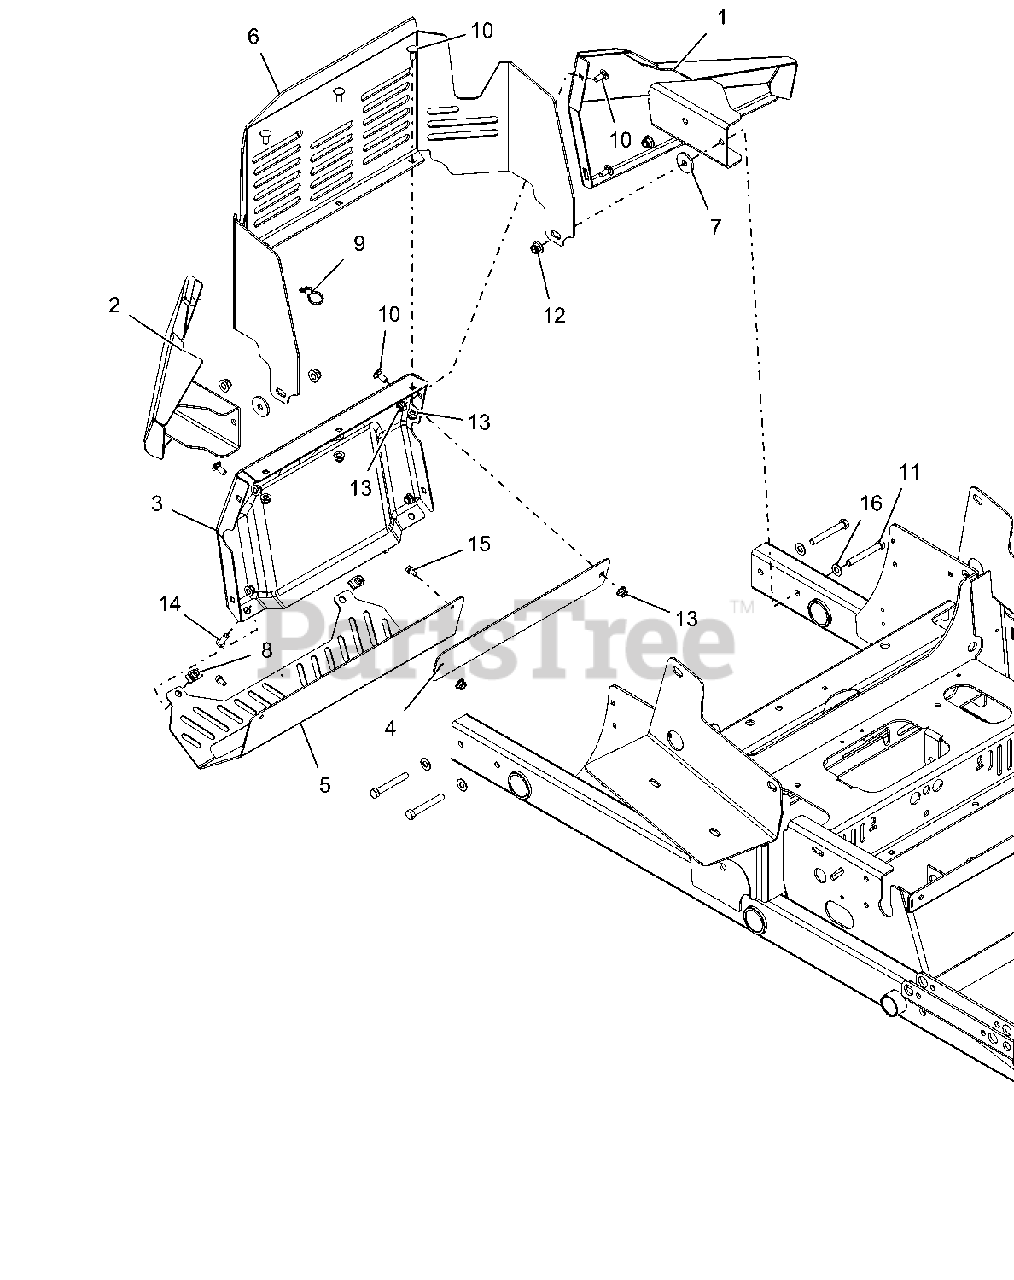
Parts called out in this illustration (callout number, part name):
1	WLDMT, LEFT REAR BUMPER WING (BLACK)
2	WLDMT, RIGHT REAR BUMPER WING (BLACK)
3	BUMPER, PT200/400 REAR (BLACK)
4	PLATE, BACKER (RED)
5	GUARD, PT200/400 MUFFLER (BLACK)
6	GUARD, PT200 ENGINE (RED)
7	WSHR-FL-STL .406X1.375X.135 YZ
8	NUT-CLIP RETAINER 5/16-18X.56
9	CABLE TIE W/ TREE (.25 HOLE)
10	BLT-RDHDSQNK .31-18X.75 G5 YWZC
11	BLT-HEX .38-16X2.75 GR5 YWZC
12	NUT-LK-NYL-FLG .38-16 YWZC
13	NUT-LK-NYL-FLG .31-18 YWZC
14	SCR-SKH .31-18X1.00 BTNHD YWZC
15	SCR-TAP .25-20X.50 HWH TR YWZ
16	WSHR-FL-STL.406X.812X.065 YWZ
